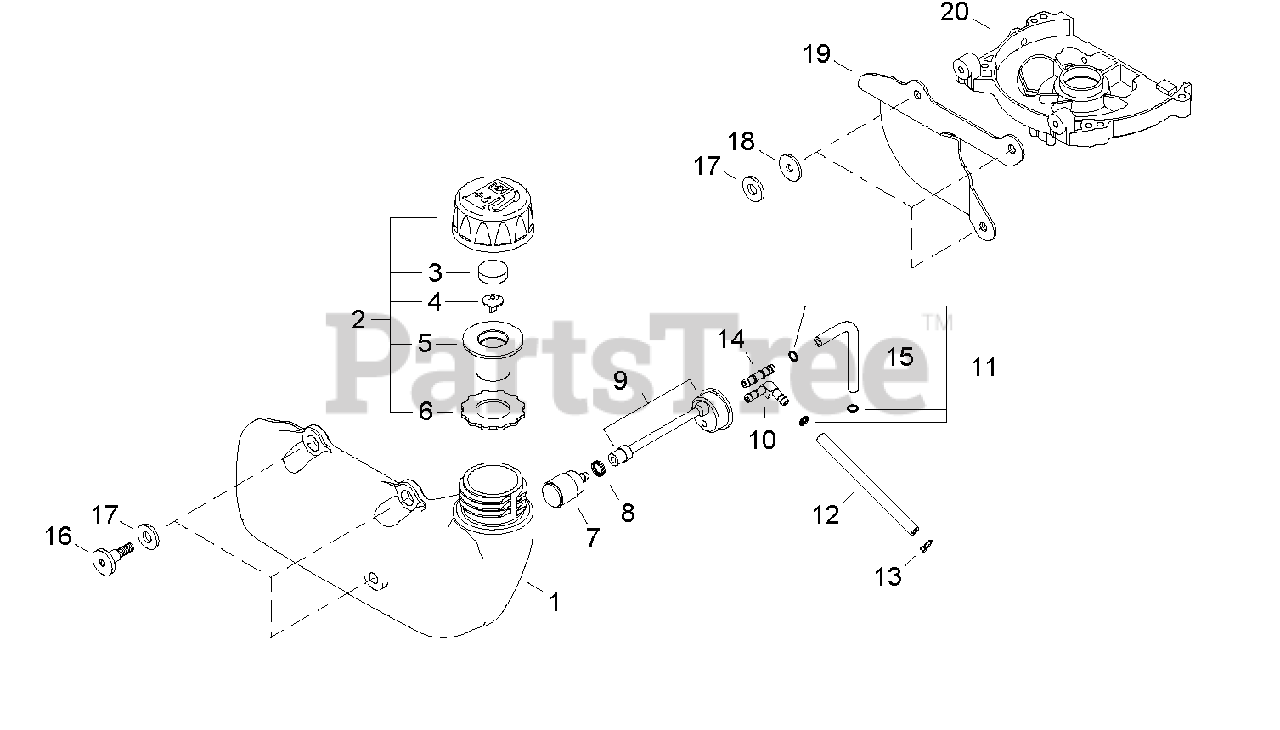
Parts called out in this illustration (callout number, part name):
1	TANK, FUEL
2	CAP ASSY
4	VENT, FUEL TANK
5	HOLDER, VENT
6	GASKET, CAP
7	FILTER, FUEL
8	CLIP - 7.8
9	FUEL PIPE ASSY
10	CONNECTOR, PIPE
11	CLIP - 6
12	PIPE - RETURN
13	CLIP - BUTTERFLY
14	CONNECTOR, PIPE
15	PIPE - FUEL
16	BOLT - 5
17	WASHER - 6
18	WASHER - 5
19	SHIELD, HEAT
20	CRANKCASE ASSY - FRONT
